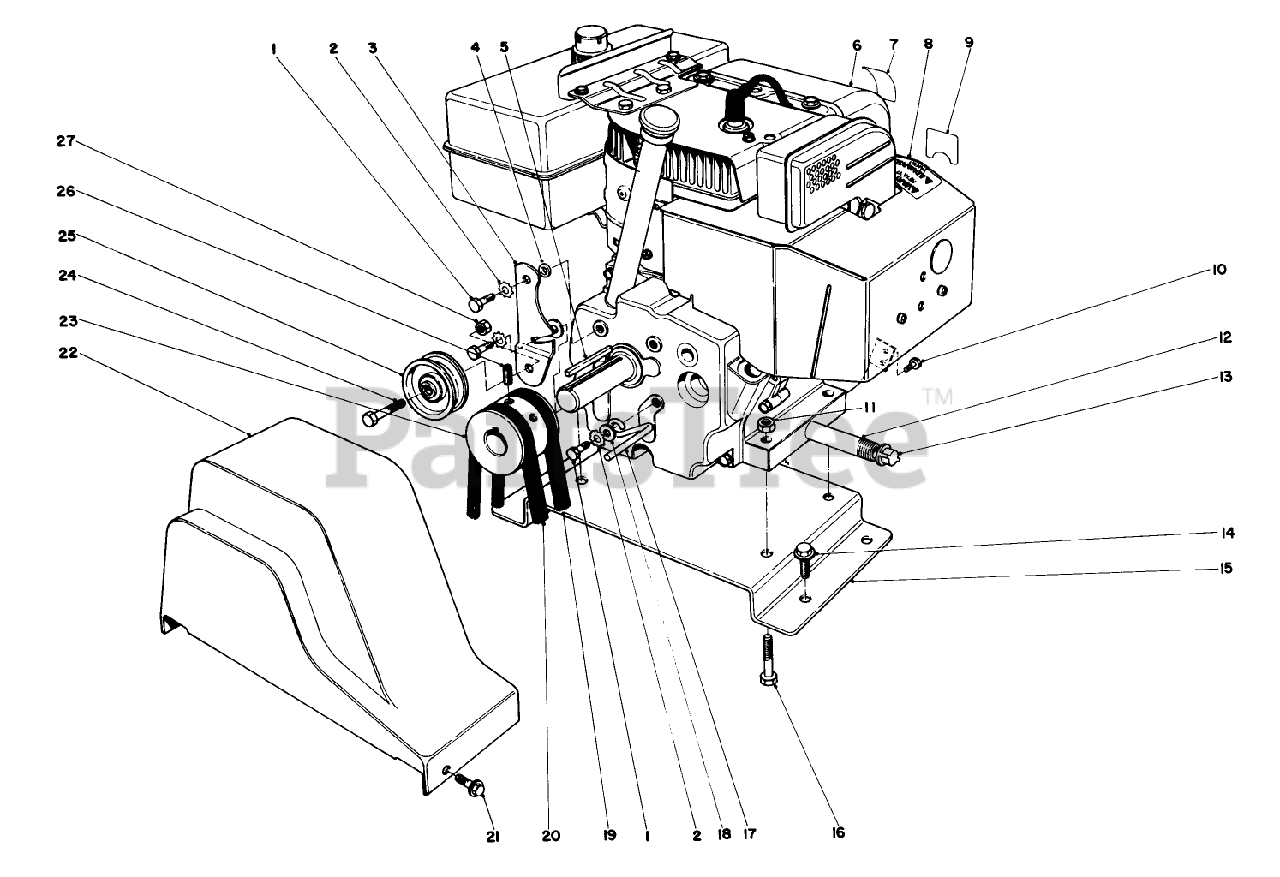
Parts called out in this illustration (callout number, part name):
1	SCREW-HH
2	WASHER-LOCK
4	SPACER
6	Engine
10	SCREW
11	NUT-LOCK, NI
12	NIPPLE-PIPE
13	CAP-PIPE
14	SCREW-HHFTF
16	SCREW-HH
18	WASHER-PLAIN
19	V-BELT
20	V-BELT
21	SCREW-HWH
24	SCREW-HH
25	PULLEY-IDLER
